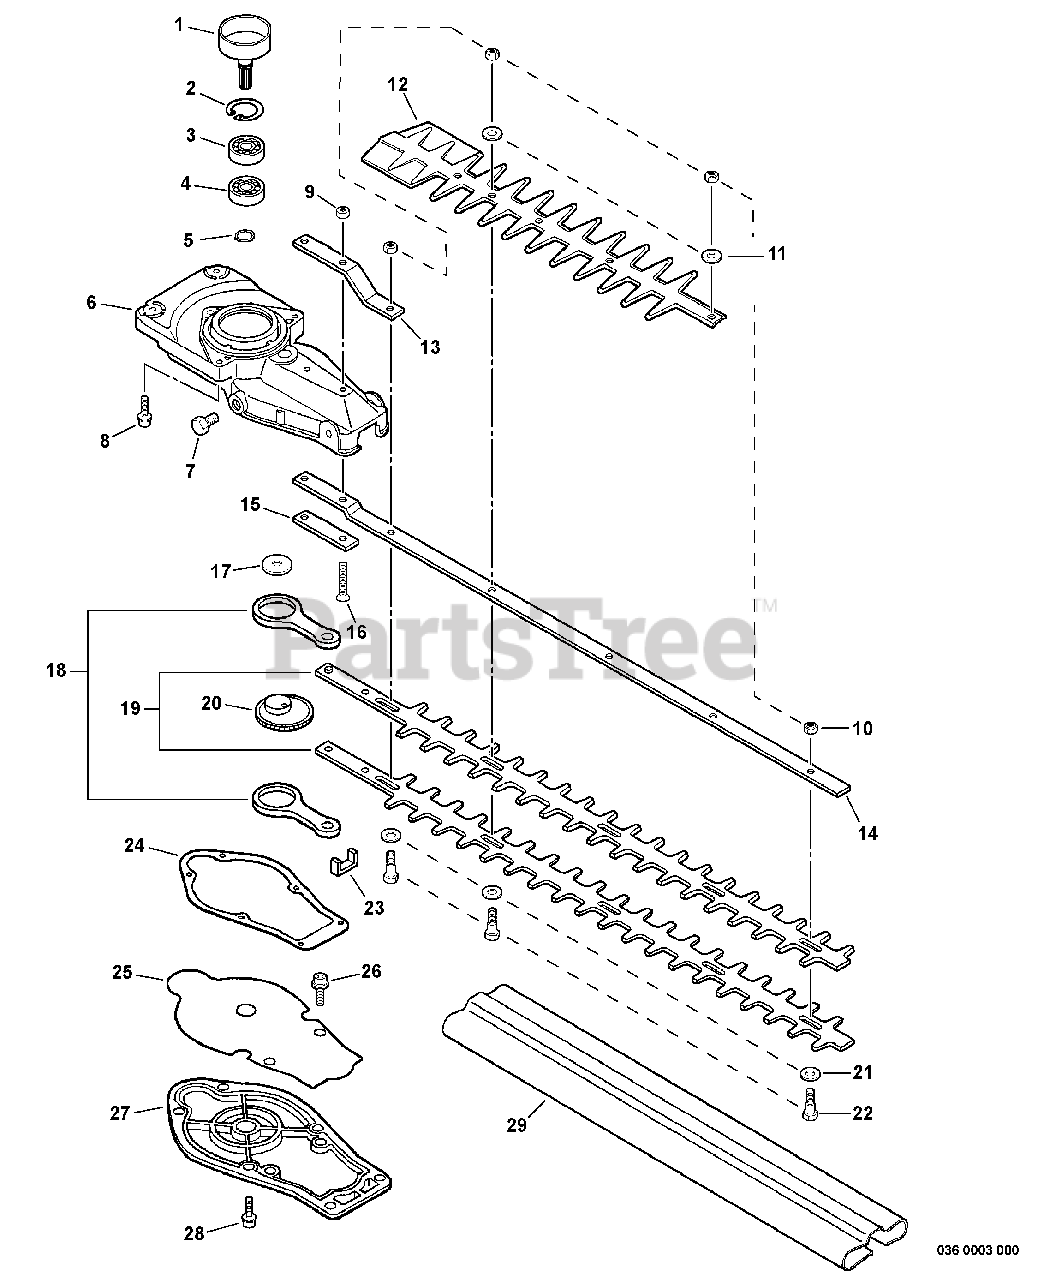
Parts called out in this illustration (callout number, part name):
1	DRUM, CLUTCH
2	RING, SNAP 35
3	BEARING, BALL 6202
4	BEARING, BALL 6202
5	RING, SNAP 14
6	CASE, GEAR
7	BOLT 8×8 SP
8	BOLT 5×25
9	NUT, HEX M6
11	WASHER 6.5×15.5×0.6
12	GUARD, CUTTER BLADE
13	PLATE, ANGLE
14	SUPPORT, BLADE
15	PLATE, EYE
16	SCREW 6×25
18	CONROD
19	BLADE, TRIMMER
21	WASHER 6.5×15.5×0.6
22	BOLT 6×20
24	GASKET, GEAR CASE
25	PLATE, GEAR CASE
26	BOLT 5×12
27	COVER, GEAR CASE
28	BOLT 4×12
29	COVER, BLADE
